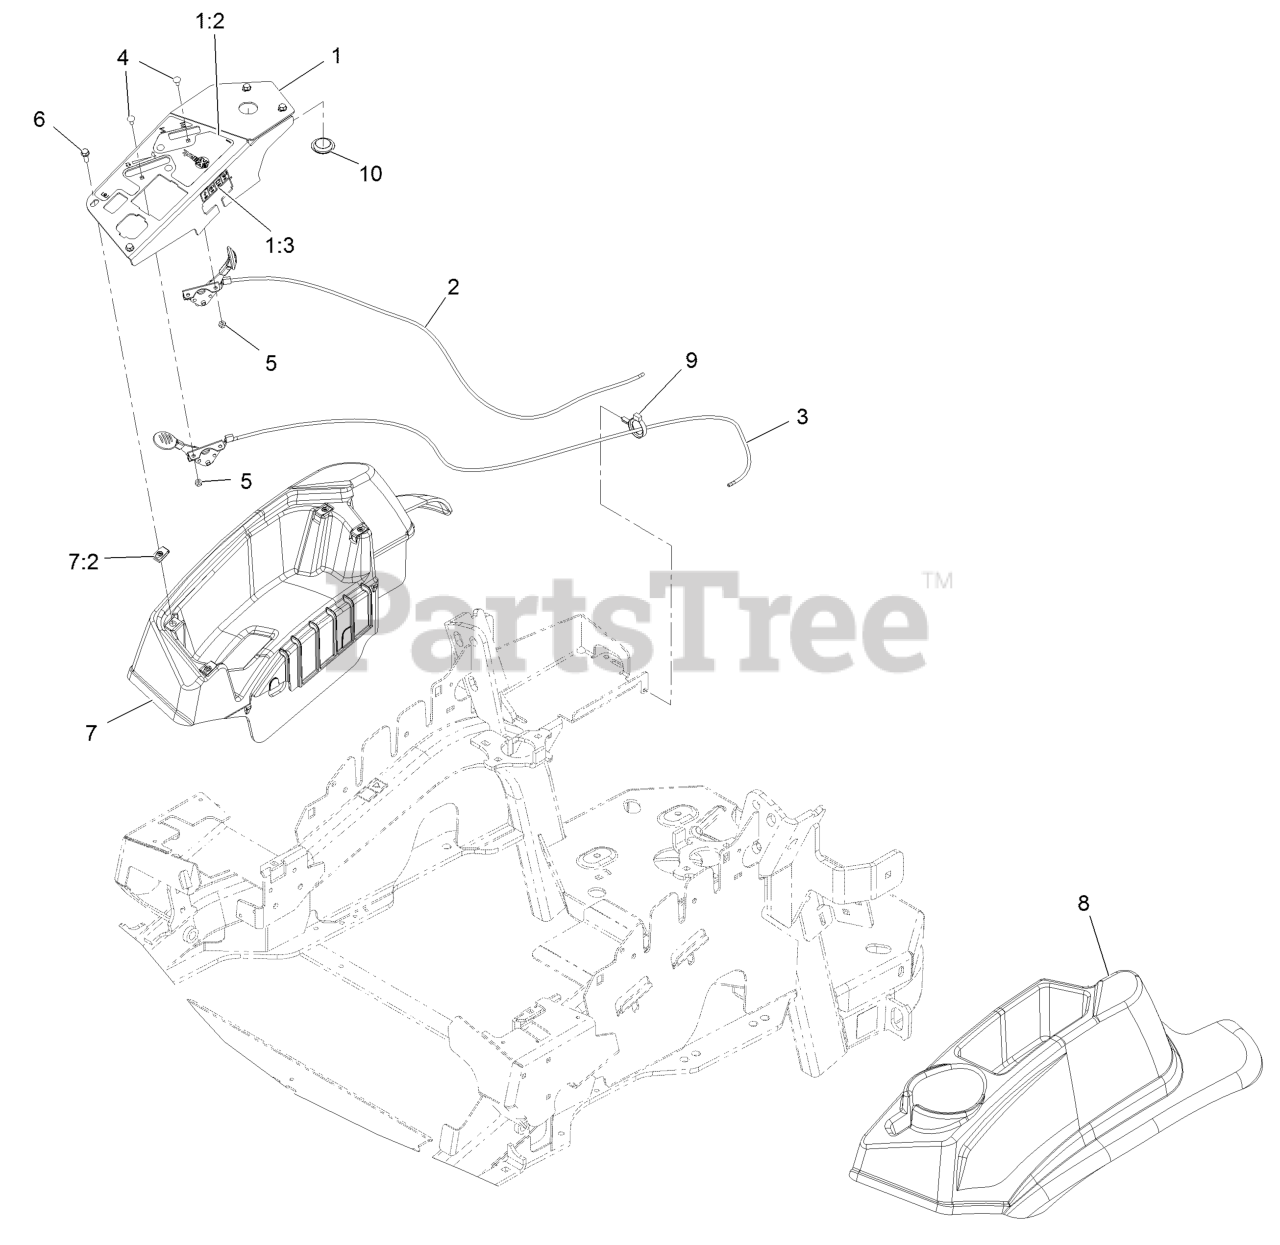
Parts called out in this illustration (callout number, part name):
1	ASM,CONSOLE PANEL W/DECAL
1:2	DECAL-CONTROL PANEL NON-E
1:3	DECAL-FUSES
2	ASM, CHOKE CABLE
3	ASM,THROTTLE CABLE
4	BOLT-CARR
5	NUT-LOCK, NI
6	SCREW-HWH
7	CONSOLE,RH AS ASM
7:2	Nut-Retainer-Panel 1/4-20
8	CONSOLE, LH AS
9	CLAMP-HOSE
10	PLUG-PLASTIC
